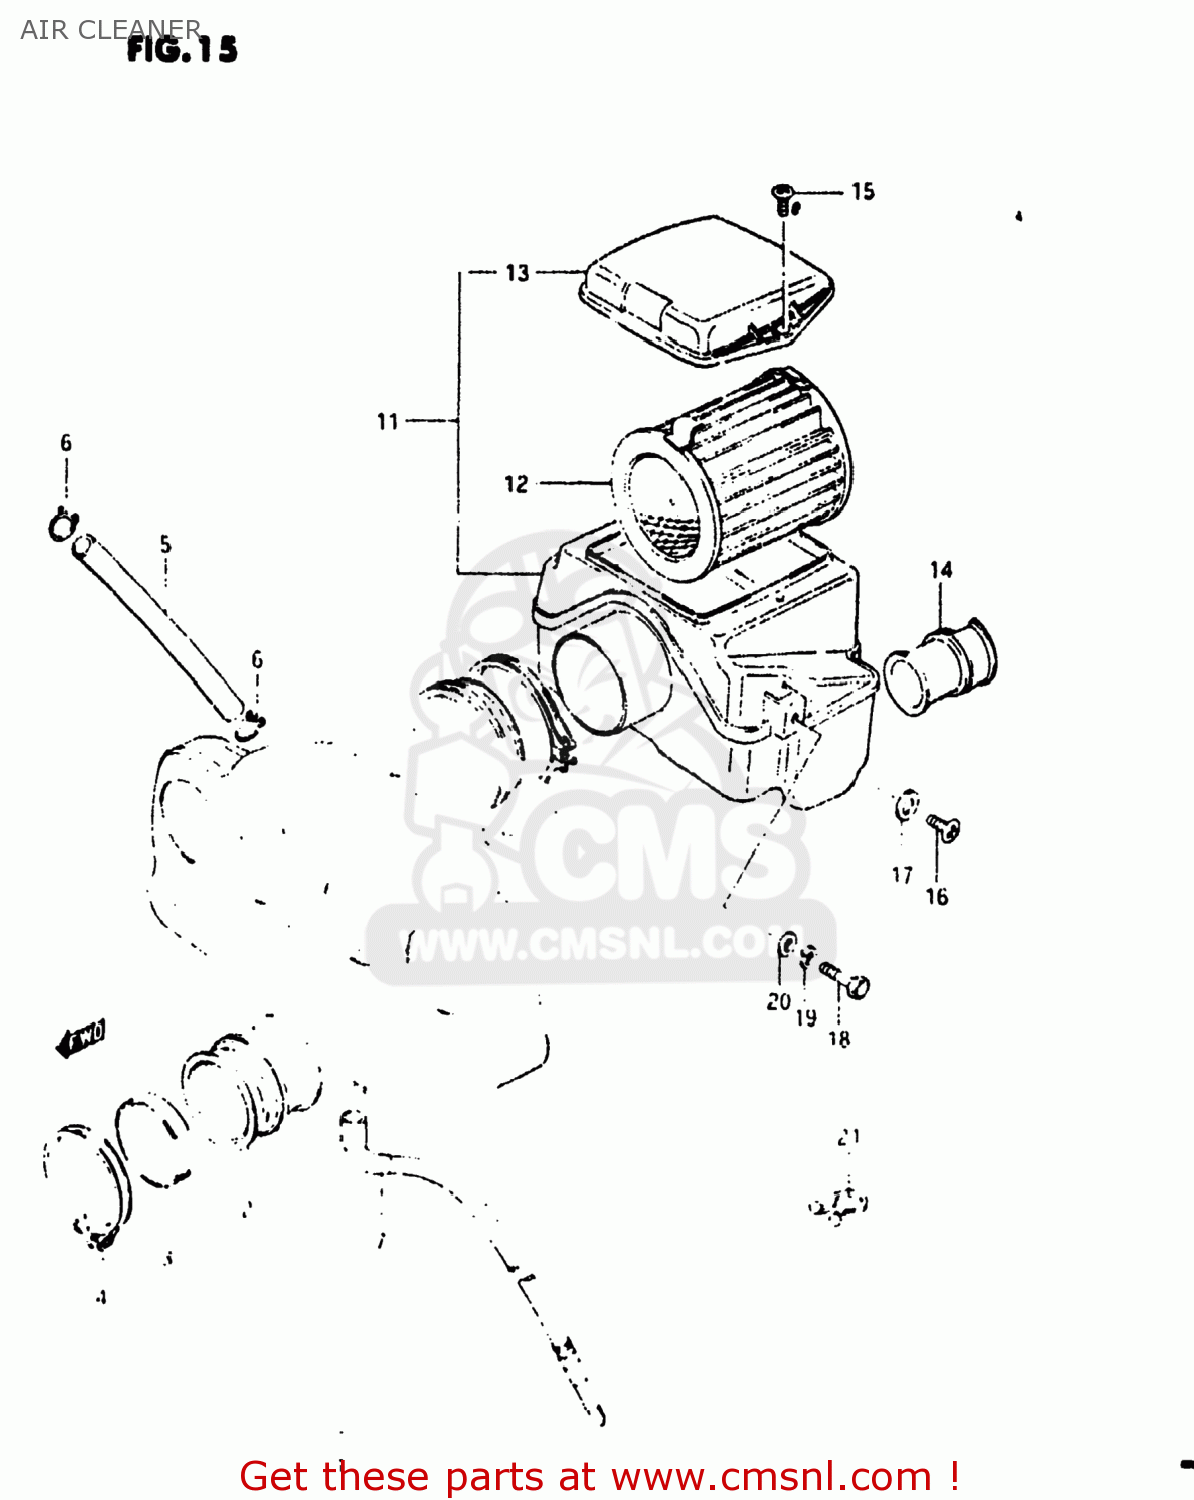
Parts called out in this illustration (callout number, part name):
1	CHAMBER ASSEMBLY,AIR CLEANER
2	TUBE,AIR CLEANER OUTLET
3	RING,CARBURETOR AIR INLET HOSE
4	CLAMP
5	HOSE,BREATHER
6	CLIP
7	DRAIN TUBE
8	CLIP
9	TUBE,JOINT
10	CLAMP
11	CASE ASSEMBLY,AIR CLEANER
12	FILTER,AIR CLEANER
13	CAP,AIR CLEANER
14	TUBE,INLET
15	SCREW M5X12 DIN 7985/N
16	SCREW
17	WASHER
18	BOLT, UPPER
19	LOCK WASHER
20	WASHER
21	CLIP
